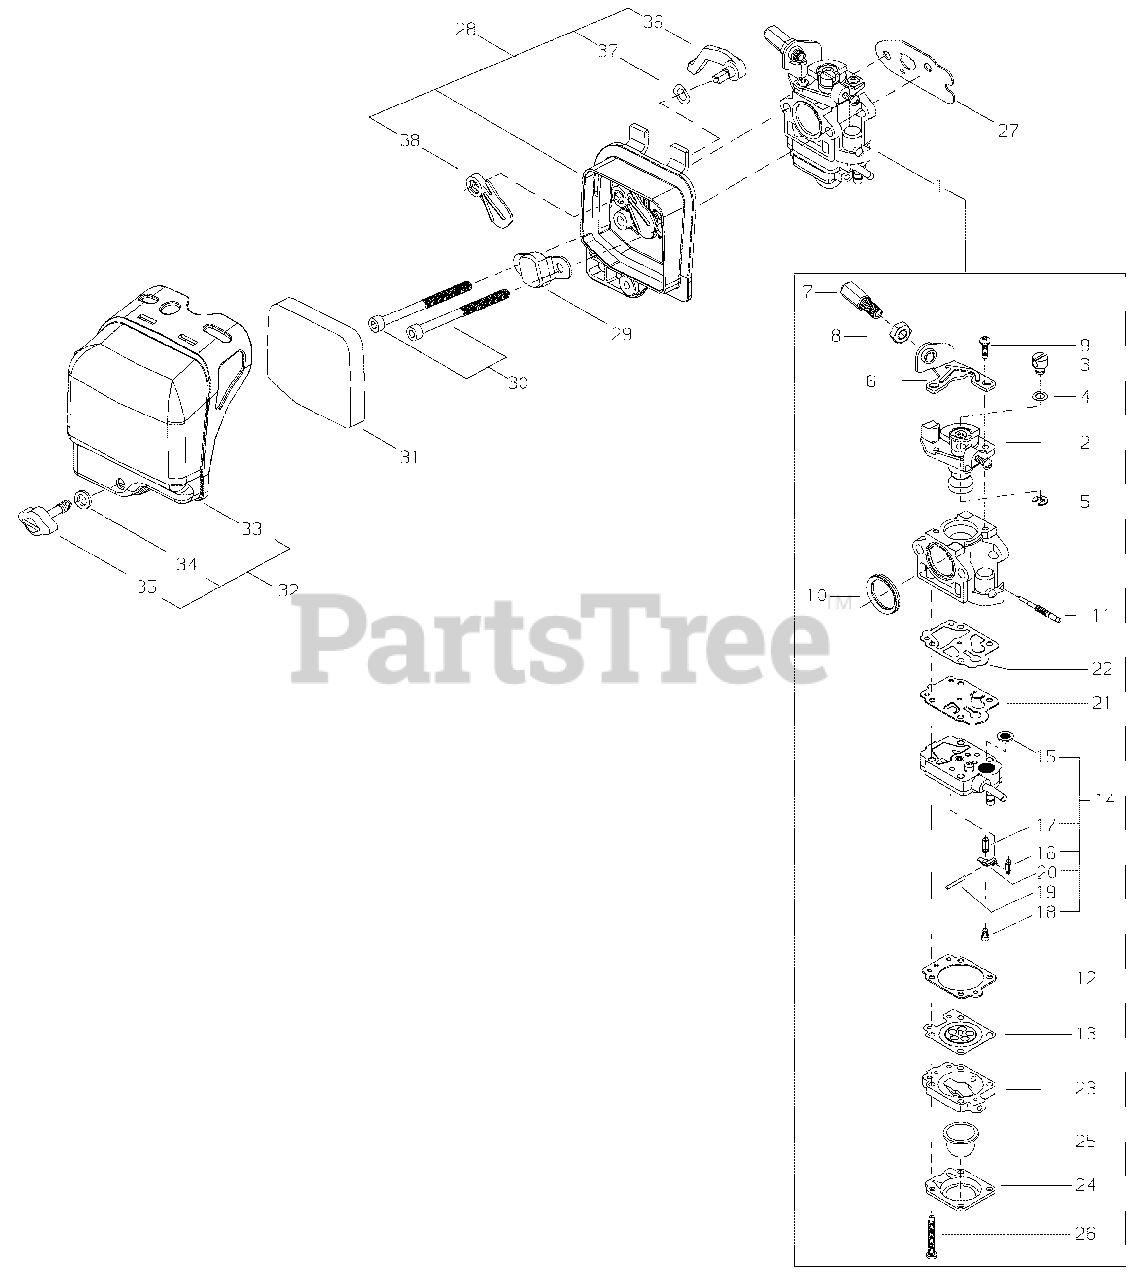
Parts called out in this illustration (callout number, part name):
1	CARBURETOR
2	VALVE ASSY, THROTTLE
3	SWIVEL
4	WASHER
5	E-RING
6	BRACKET, THROTTLE CABLE
7	ADJUSTER, THROTTLE CABLE
8	NUT, ADJUSTER LOCK M7
9	SCREW
10	RING, PACKING
11	NEEDLE, HIGH SPEED
12	GASKET, METERING DIAPHRAGM
13	DIAPHRAGM, METERING
14	BODY ASSY, PUMP
15	SCREEN, FUEL INLET
16	VALVE, INLET NEEDLE
17	SPRING, METERING LEVER
18	SCREW
19	PIN, METERING LEVER
20	LEVER, METERING
21	DIAPHRAGM, PUMP
22	GASKET, PUMP
23	BODY ASSY, PURGE
24	RETAINER, PURGE BULB
25	BULB, PURGE
26	SCREW
27	GASKET, CARBURETOR
28	AIR FILTER CASE ASSY
29	BRACKET
30	BOLT M5×60
31	FILTER, AIR
32	COVER ASSY, AIR FILTER
33	COVER, AIR FILTER
34	WASHER 5
35	THUMBSCREW
36	LEVER, CHOKE
37	WASHER, WAVE
38	PLATE, CHOKE
